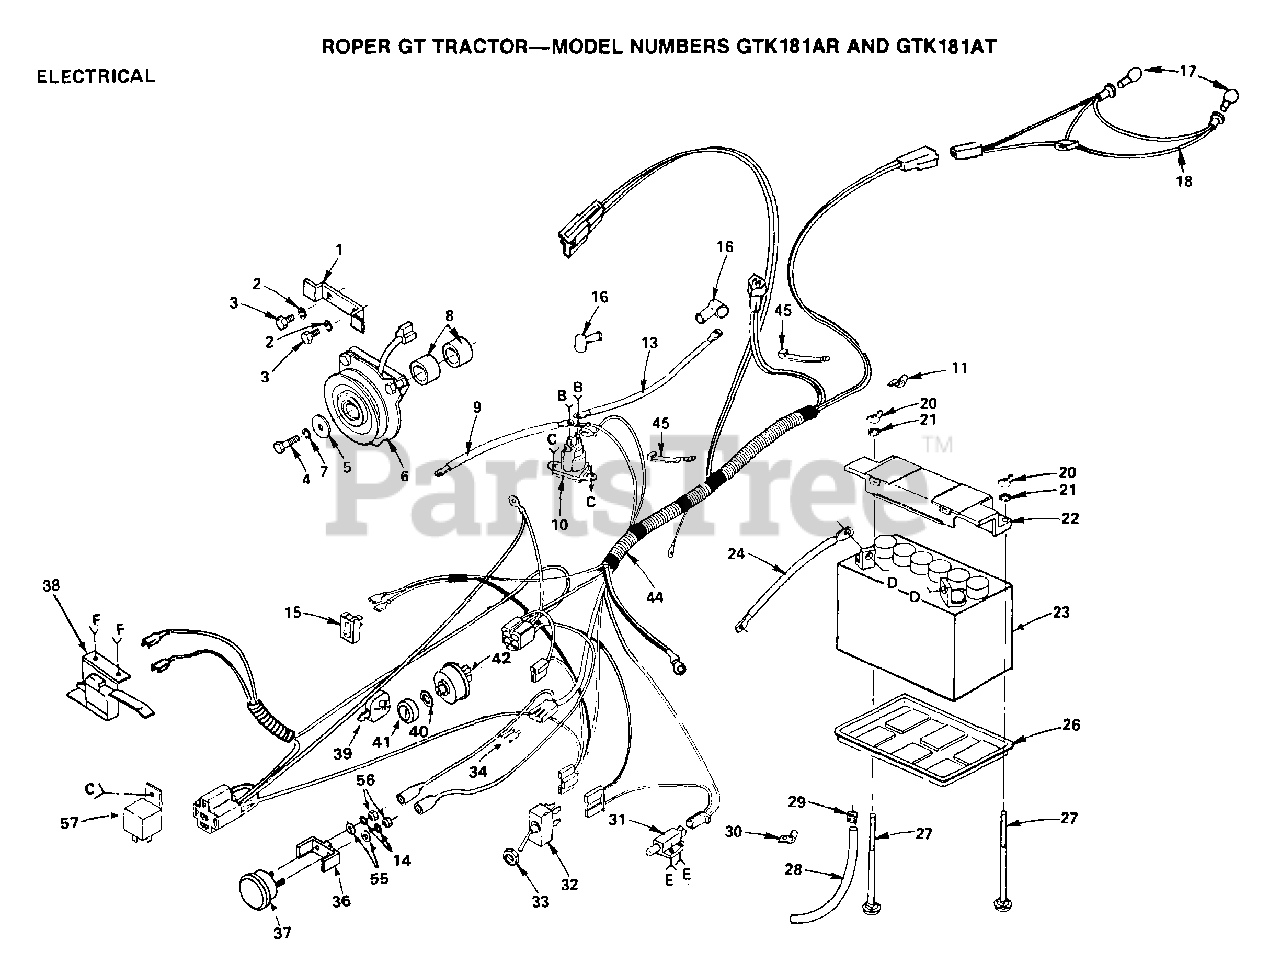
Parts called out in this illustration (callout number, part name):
2	LOCKWASHER
3	BOLT
4	No Desciption for Part
6	CLUTCH.ELECTRIC.T
7	LOCKWASHER
8	SPACER-CLUTCH GT
9	CABLE-BATTERY T
15	SWITCH LT
18	HARNESS T
21	LOCKWASHER GT
24	CABLE T
26	"TRAY T, BATTERY"
27	BOLT
29	HOSE CLAMP T
30	CLIP GTV
31	SWITCH-INTER. GT
32	SWITCH.PTO.T
33	HEX NUT T
34	FUSE-30 AMP
37	AMMETER T
45	WIRE TIE
55	WASHER
57	RELAY ASSY T
